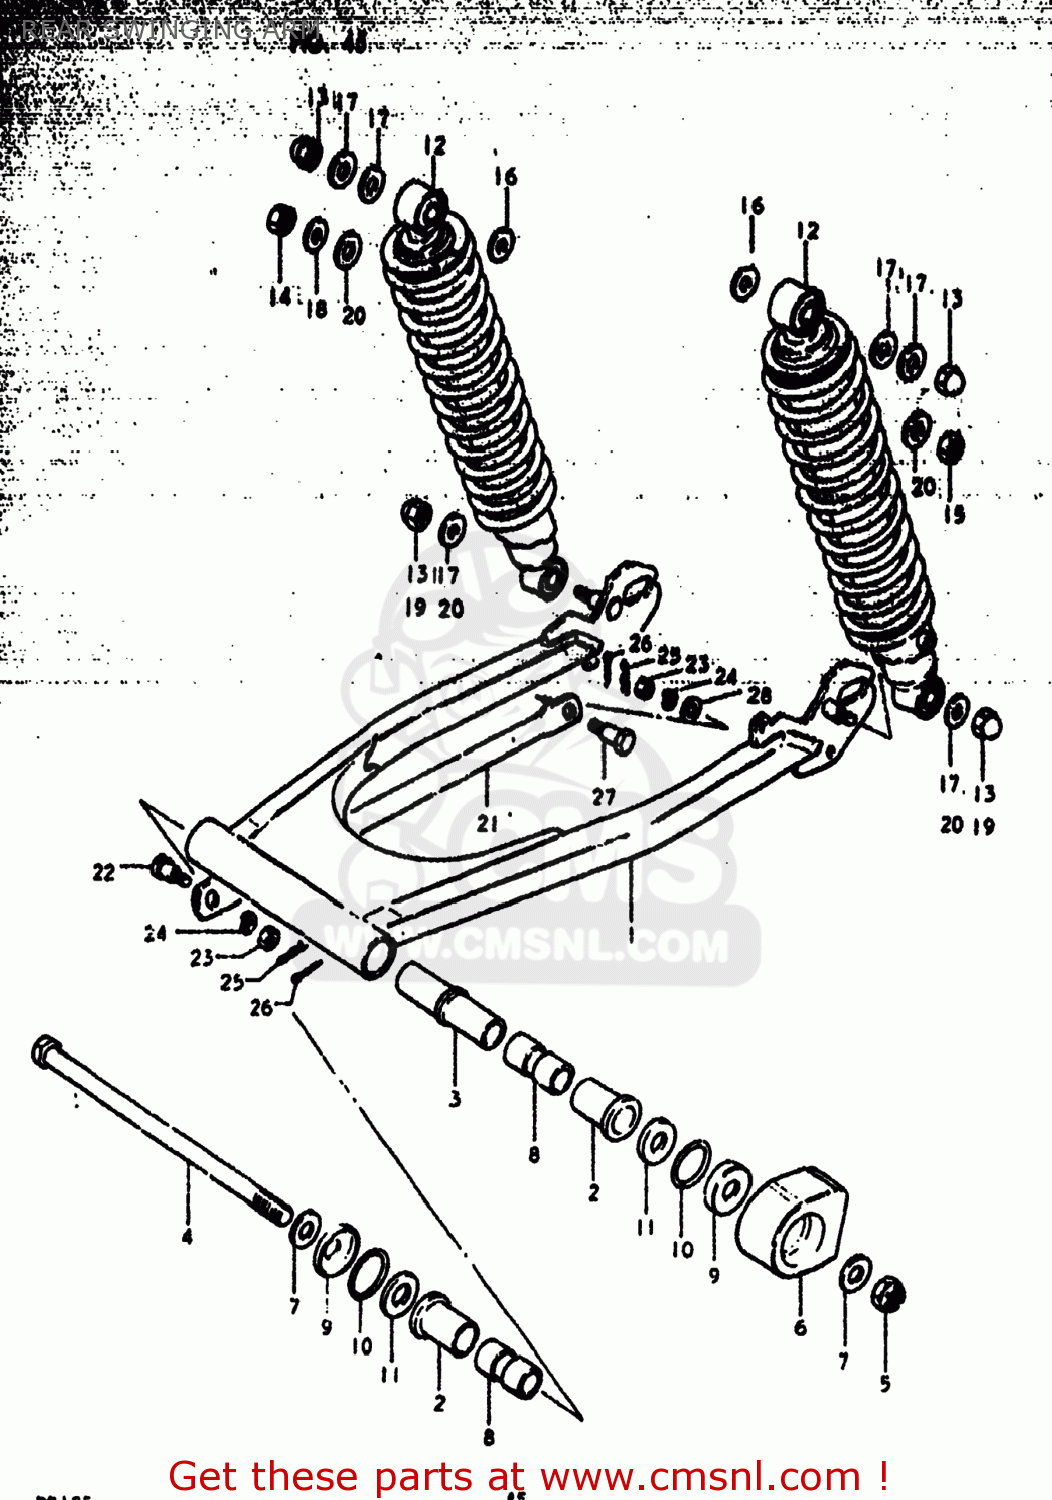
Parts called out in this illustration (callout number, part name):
1	SWING ARM ASSEMBLY,REAR
2	BUSH
3	SPACER,RR SWGARM PIVOT CTR
4	SHAFT,REAR SWING ARM
5	NUT
6	BUFFER,CHAIN TOUCH DEFENSE
7	WASHER
8	SPACER,RR SWGARM PIVOT
9	COVER,SWGARM BUSH DUST SEAL
10	O RING(D:2,ID:24.5)
11	WASHER(12.5X24X2.3)
12	ABSORBER ASSEMBLY,REAR SHOCK
13	NUT, LOWER LH
14	NUT
15	NUT
16	WASHER
17	WASHER
18	WASHER (12.5X24X3.2)
19	NUT, LOWER LH
20	WASHER
21	TORQUE LINK,REAR
22	BOLT(8X26.5)
23	NUT
24	LOCK WASHER
25	CLIP
26	PIN
27	BOLT(8X22)
28	WASHER
